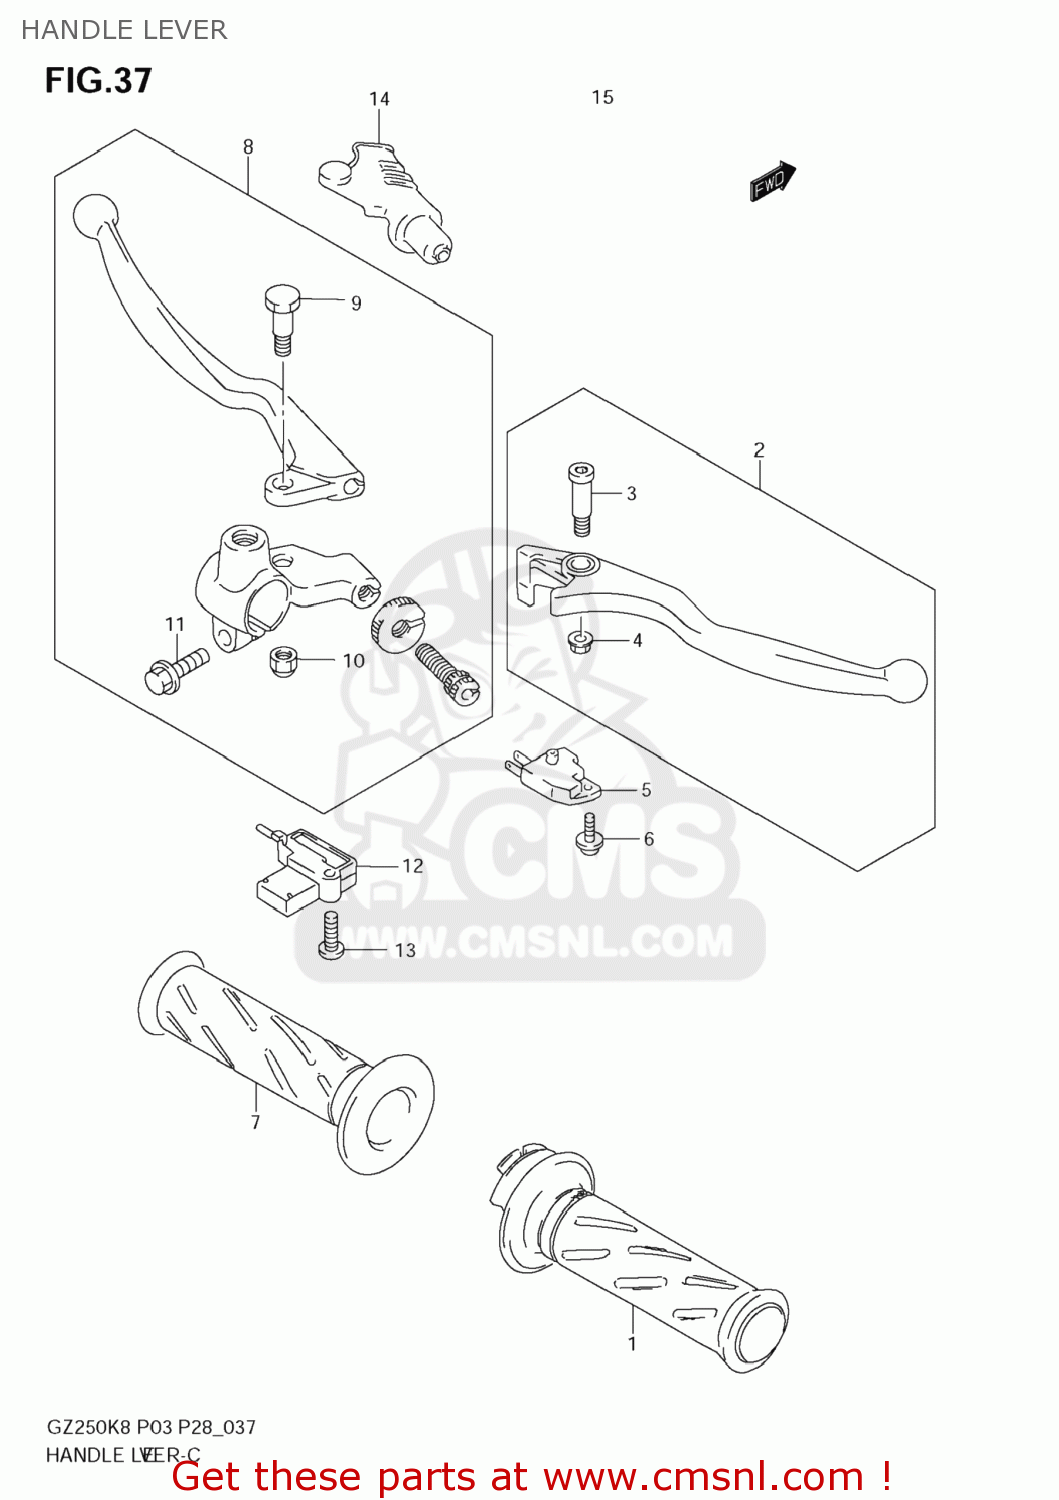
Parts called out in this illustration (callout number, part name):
1	GRIP, THROTTLE
2	LEVER ASSY, BRAKE
3	BOLT, PIVOT
4	NUT
5	SWITCH ASSY,ST
6	SCREW
7	GRIP LH
8	LEVER ASSY, CLUTCH
9	BOLT, PIVOT
10	NUT
11	BOLT
12	SWITCH,CLUTCH
13	SCREW
14	COVER,CLUTCH LEVER
